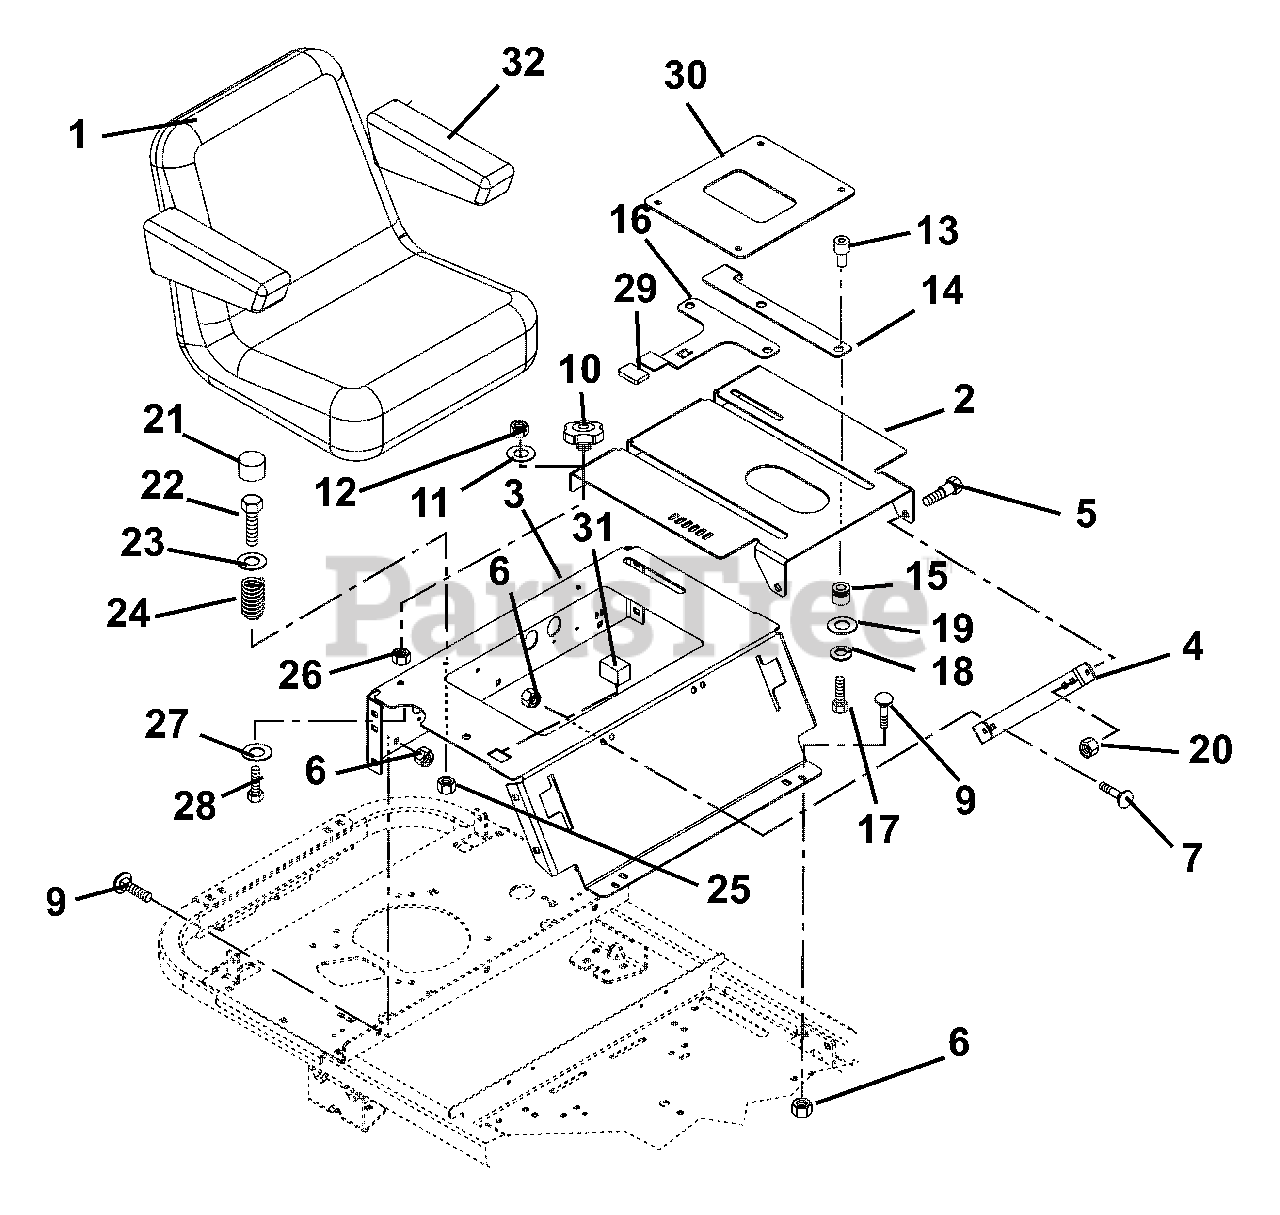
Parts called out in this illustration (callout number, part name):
1	Seat with Arm
2	Seat Plate
3	Seat Support
4	Bracket, Seat Plate
5	Bolt, Shoulder .375-16 x .135
6	Nut .38-16 Flange Nyloc
7	Bolt, Round Head Square Neck .38-16 x 1.00 Grade 5
8	Hour Meter, Quartz
9	Bolt, Round Head Square Neck .38-16 x 1.00 Grade 5
10	Knob, Clamping .312-18 Nyloc
11	Washer-Flat-Steel .328 x 1.00 x .094
12	Nut, Locking Nylon .312-18
13	Spacer, Seat Top
14	Seat Stop
15	Spacer, Seat Bottom
16	Lever, Seat Adjustment
17	Bolt-Hex .31-18 x 2.25 Grade 5
18	Washer-Locking .31 x .078 Regular
19	Washer-Flat-Steel .344 x1.375 x .075
20	Nut, Locking Top Flange .38-16
22	Bolt-Hex .31-18 x 1.00 Grade 5
23	Washer-Flat-Steel .344 x .688 x .065
24	Spring, Compression 2.9 x 2.02 O.D.
25	Nut 5/16-18 Flange Nyloc
26	Nut-Spin Lock-Flange .312-18
27	Washer-Flat-Steel .505 x 1.00 x .062
28	Bolt-Round Head Square Neck .31-18 x 3.50 Grade 5
30	Seat Support Plate
31	Plug, Headlight Switch
32	Armrest
